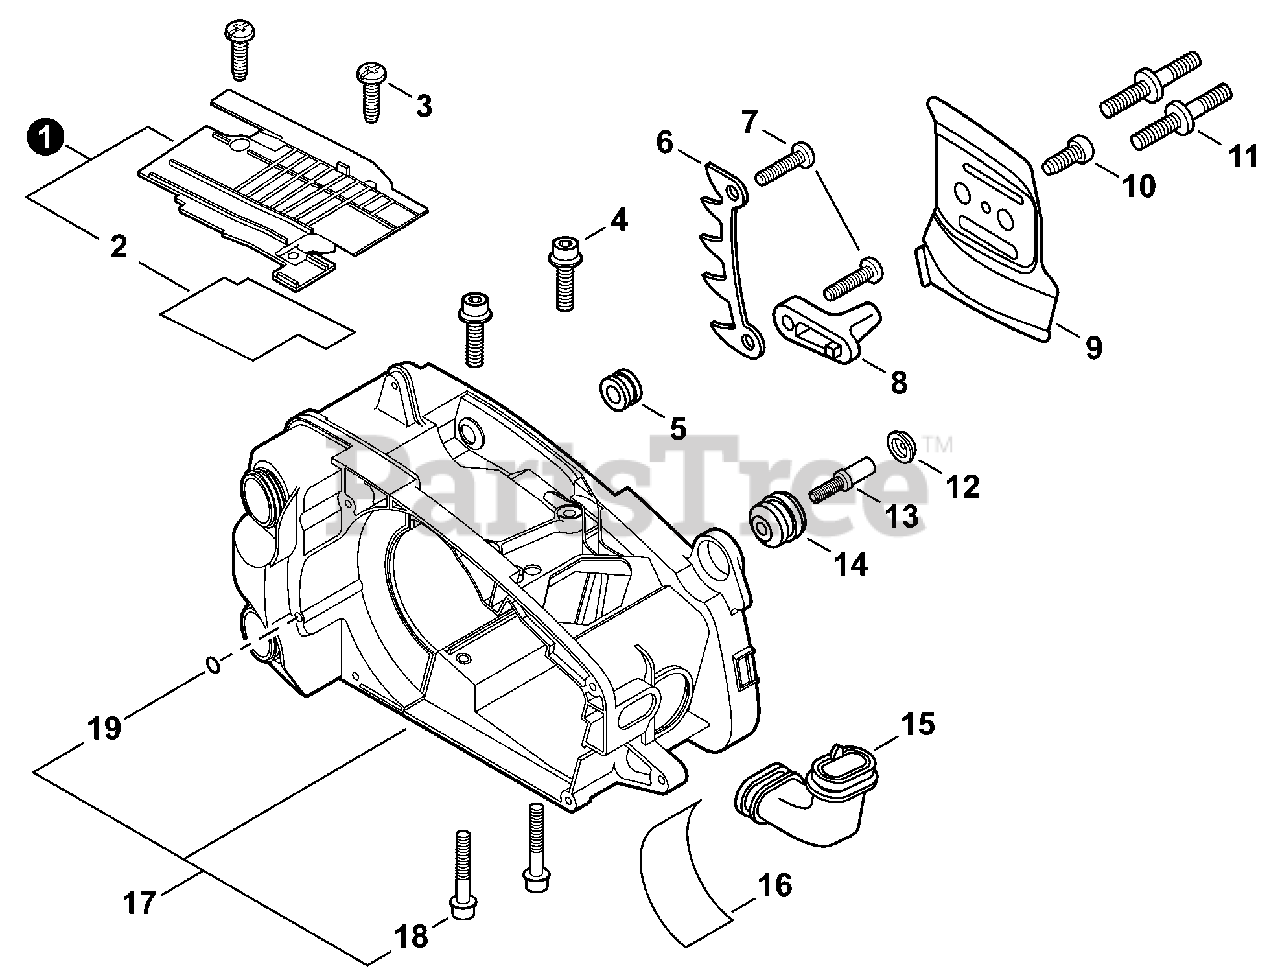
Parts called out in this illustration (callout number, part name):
1	COVER SET, DUST
2	SHIELD, HEAT
3	SCREW 4×12
4	BOLT 5×20
6	SPIKE, BUMPER
7	SCREW 5×20
8	CHAIN CATCHER
9	PLATE, GUIDE - INNER
10	SCREW 4×10
11	BOLT, STUD 6
12	CAP, CUSHION
13	BOLT 4×15
14	CUSHION
15	PIPE, INTAKE
16	CUSHION
17	COVER KIT, ENGINE
18	BOLT 5×30
19	O-RING S-4
